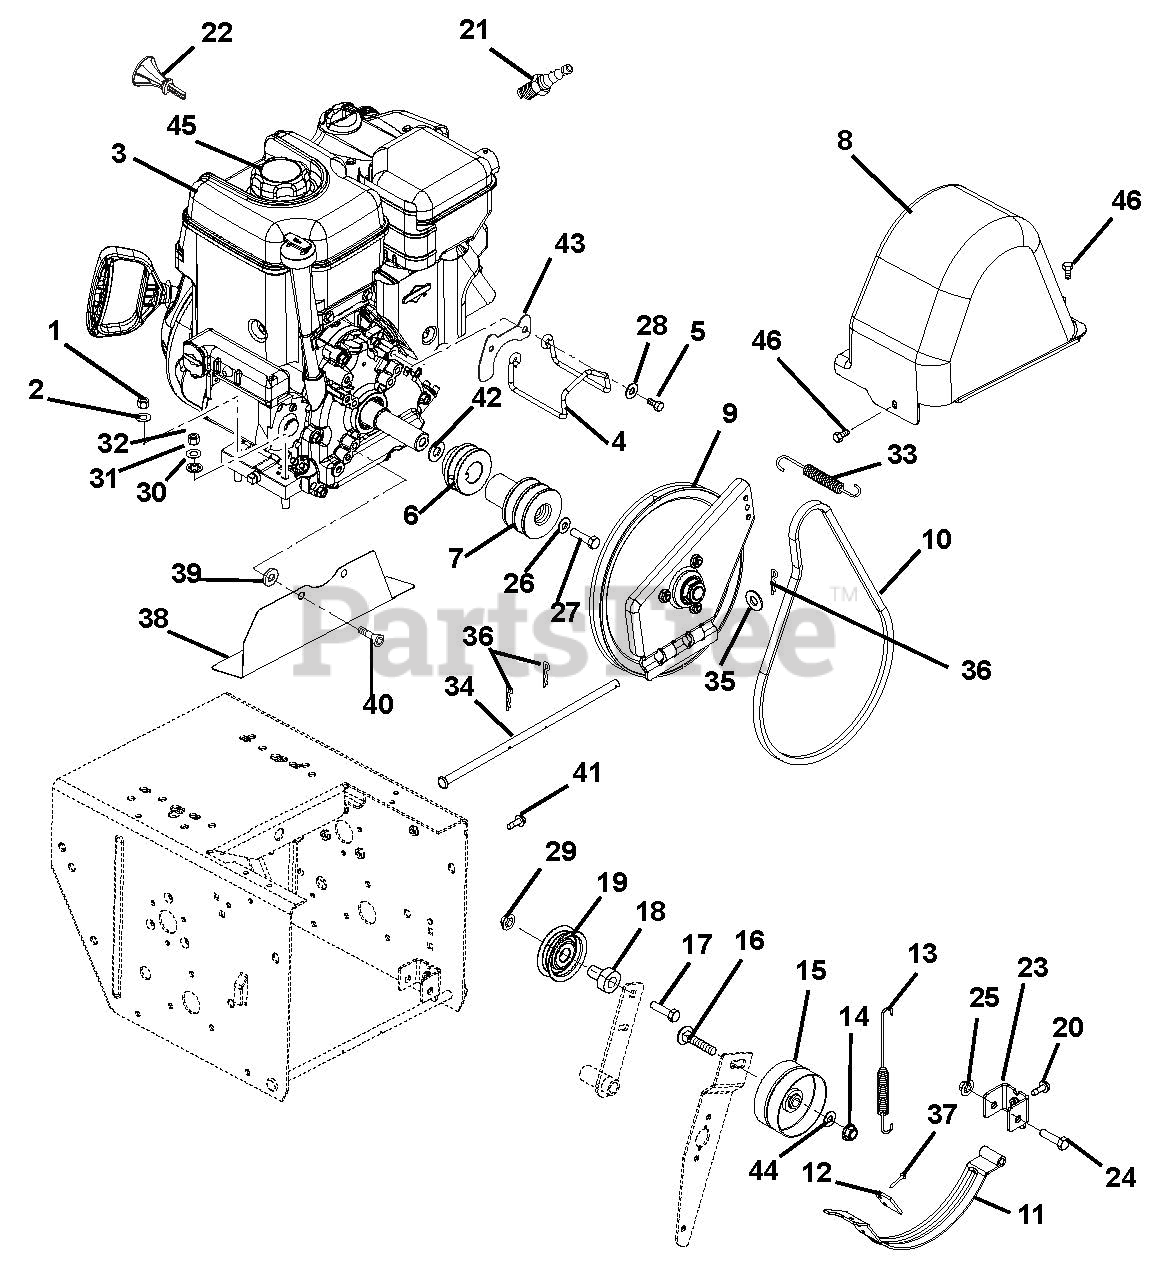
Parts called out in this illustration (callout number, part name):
1	@NUT-HEX .31-18 YWZC
2	WSHR-LK .312X.097 HVY YWZC
3	ENGINE, BRIGGS SNOW 1450, 120V
3	ENGINE, BRIGGS SNOW 1550, 120V
3	ENGINE, BRIGGS SNOW 1650, 120V
3	ENGINE, BRIGGS SNOW 1550, 240V
3	ENGINE, BRIGGS SNOW 1650, 12V
4	FINGER, BELT
5	BLT-HEX .31-24X.75 YWZC GR5
6	SHEAVE, DRIVE
7	SHEAVE, ATTACHMENT 2-GRV
8	COVER, BELT
9	PLATE, SWING ASSEMBLY-DEEP
10	V-BELT, 3L-WRAPPED
11	ARM, BRAKE-ATTACHMENT
12	PAD, BRAKE
13	SG-TENS .056X.60X4.40
14	@NUT-LK-CTR-JAM .375-16 YWZC
15	IDLER, FLAT-2.75 OD X .375 ID
16	@BLT-RHDSSQNK .38-16X1.75 G5YZ
17	@BLT-HEX .31-18X1.25 GR5 YWZC
18	SPCR, BRG .315X.50X.688X.281
19	IDLER
20	SCR-TAP .25-20X.50 HWH TR YWZ
21	PLUG, SPARK
22	KEY, PUSH/PULL BRIGGS
22	KEY, IGNITION ROTARY B&S
23	PIVOT, BRAKE
24	@BLT-HEX .31-18X2.00 GR5 YWZC
25	@NUT-LK-TOP-FLG .31-18 YWZC
26	@WSHR-LK .38X.094 REG YWZC
27	BLT-HEX .38-24X2.25 YWZC GR5
28	WSHR-LK .312X.097 HVY YWZC
29	@NUT-LK-TOP-FLG .31-18 YWZC
30	WSHR-LOCK INT .31 YWZC
31	@WSHR-FL-STL.344X.688X.065YWZC
32	@NUT-LK-CTR .31-18 YWZC
33	SG-TENS .048X.50X2.8
34	PIN, PIVOT
35	@WSHR-FL-STL.406X.812X.065 YWZ
36	PIN-HAIR, ENDRIES #25 YWZC
37	RVT-POP .187 YZ
38	BAFFLE, ENGINE
39	WSHR-FL-STL .536X1.07X.109 YZ
40	SCR-MCH.31-24X.75FLCTRSK EP80
41	@SCR-TAP .25-20X1.50 HWH TR YZ
42	WSHR-FL-STL- 1.062X2.0X.134 YZ
43	GUARD, BELT COVER - BRIGGS
44	@WSHR-FL-STL.38X.875X.083 YWZC
45	CAP, FUEL - BRIGGS & STRATTON
46	SCR-TAP .25-20X.50 LGHWH TR YZ
